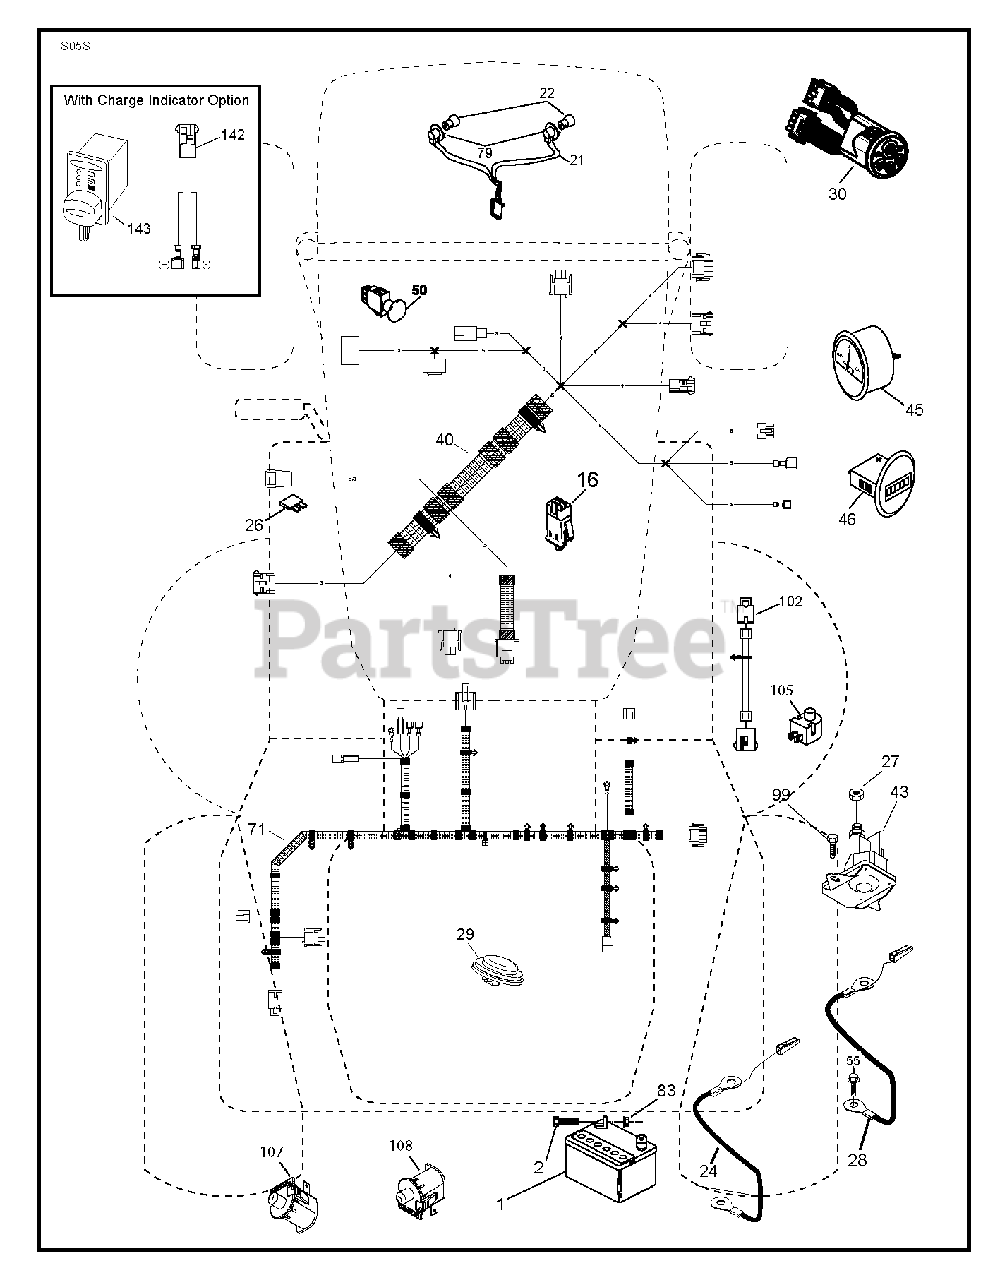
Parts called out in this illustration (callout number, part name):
1	BATTERY BATTERY 14AH 12V LEOC
2	SCREW.HEX.HEAD.CAP.M6 X1.12W
16	SWITCH INTERLOOK PUSH-IN
21	HARNESS.LIGHT W/4152J BULBS
24	CABLE.BATTERY.POASTIVE.HAM.POS
26	FUSE 20AMP
27	NUT
28	CABLE.GROUND, BATT TO HARN
29	SWITCH.SEAT.OPC.GRY.BUTTON/CAP
30	SMART SWITCH MY14 CRD
40	HARNESS.CHAS.TEX.SIS.FBAT.TWIN
43	SOLENOID.W/BRASS.PLUNGER
45	AMMETER GAUGE ROUND SNAP-IN
46	HOURMETER.GAUGE.RNK.SNAPIN.LS
50	RB PTO.SWITCH.8 TERMINAL.BLACK
55	SCREW 5/16"
71	HARNESS CHAS,TEX,SIS,CRD SMART
79	BULB HOLDER ASM.
83	NUT NUT SQUARE
99	SCREW
102	HARNESS ASSY
105	REVERSE SWITCH
107	.WITCH.FULL BAGGER.INDICATOR
108	SWITCH.SNAPMOUNT.NC
142	RP HARNESS.JUMPER.CTEK
